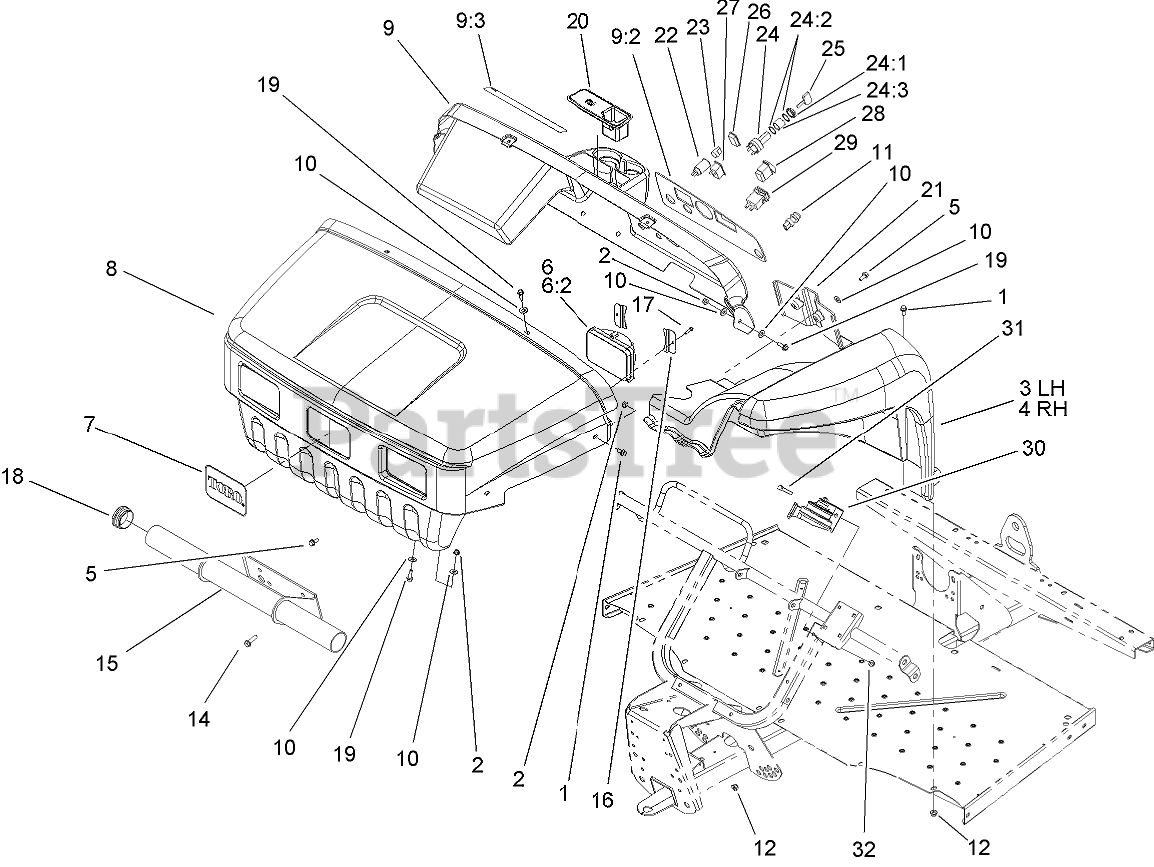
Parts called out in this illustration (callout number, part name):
1	SCREW-HHF
2	NUT-HF, NI
3	LH FENDER ASM
4	RH FENDER ASM
5	SCREW-HHF
6	HEADLIGHT
6:2	LENS-HEADLIGHT
7	DECAL
8	HOOD ASM
9	DASH ASM
9:2	DECAL-WARNING
9:3	DECAL-DANGER
10	WASHER-FLAT
11	BUTTON-HORN
12	NUT-HF, NI
15	BUMPER-TUBE
16	BRACKET-HEADLIGHT
17	SCREW-HWH
18	CAP-END
19	SCREW-HHF
20	PLUG-RUBBER
21	COVER-CHANNEL
22	POINT-POWER
24	Switch-Ignition
24:1	NUT-SWITCH, PLASTIC
24:2	WASHER-LOCK, INTERNAL
24:3	SPACER-SWITCH
25	KEY-IGNITION
26	PLUG-HOLE
27	INDICATOR-LIGHT, LOW-OIL PRESSURE
28	SWITCH
29	HOURMETER
31	SCREW-HH
32	NUT-HF, NI
